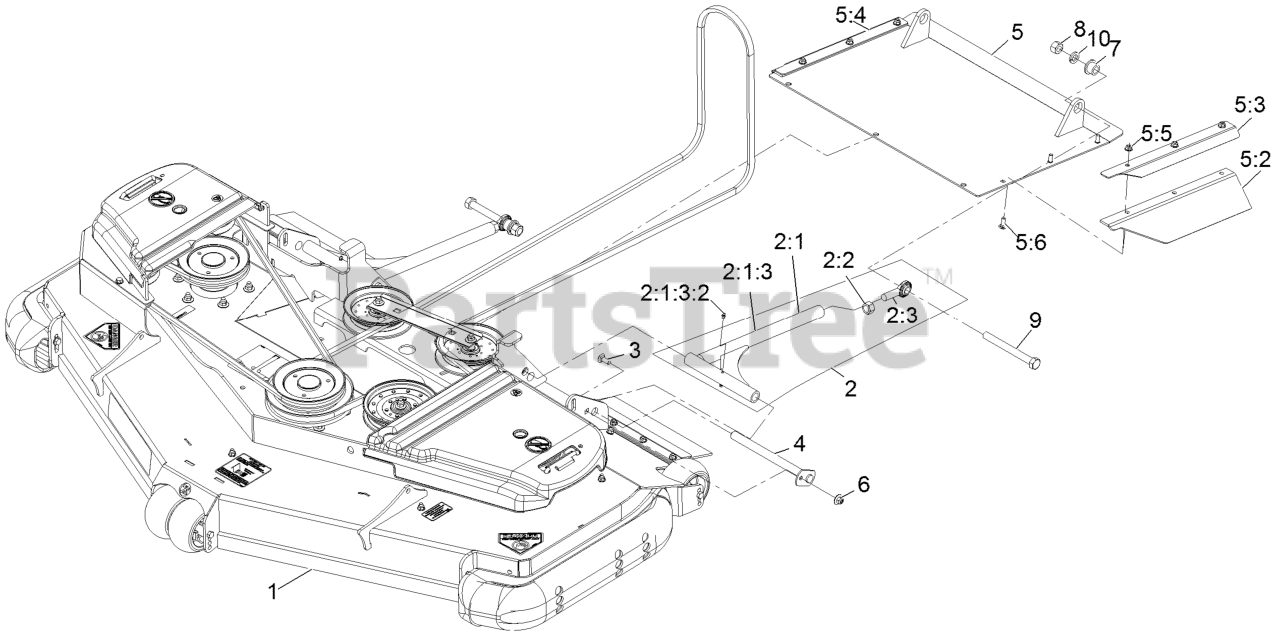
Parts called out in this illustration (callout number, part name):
1	ASM-Deck Complete Rd60
2	ASM,DECK STRUT XS 60
2:1	STRUT-DECK
2:1:3	Tube And Zerk ASM
2:2	NUT-HEX
2:3	BALLJOINT-SPHERICAL
3	BOLT-CARR
4	PIN-STRUT
5	ASM-DISCHARGE TUNNEL RD60
5:2	FLAP-RD TUNNEL SIDE
5:3	BRKT-RD TUNNEL FLAP LH
5:4	BRKT-RD TUNNEL FLAP RH
5:5	NUT-HF, NI
5:6	SCREW-CARR
6	Nut-Nyloc 3/8-16 Flg
7	BUSHING-FLANGE
8	NUT-HEX
10	WASHER-LOCK
